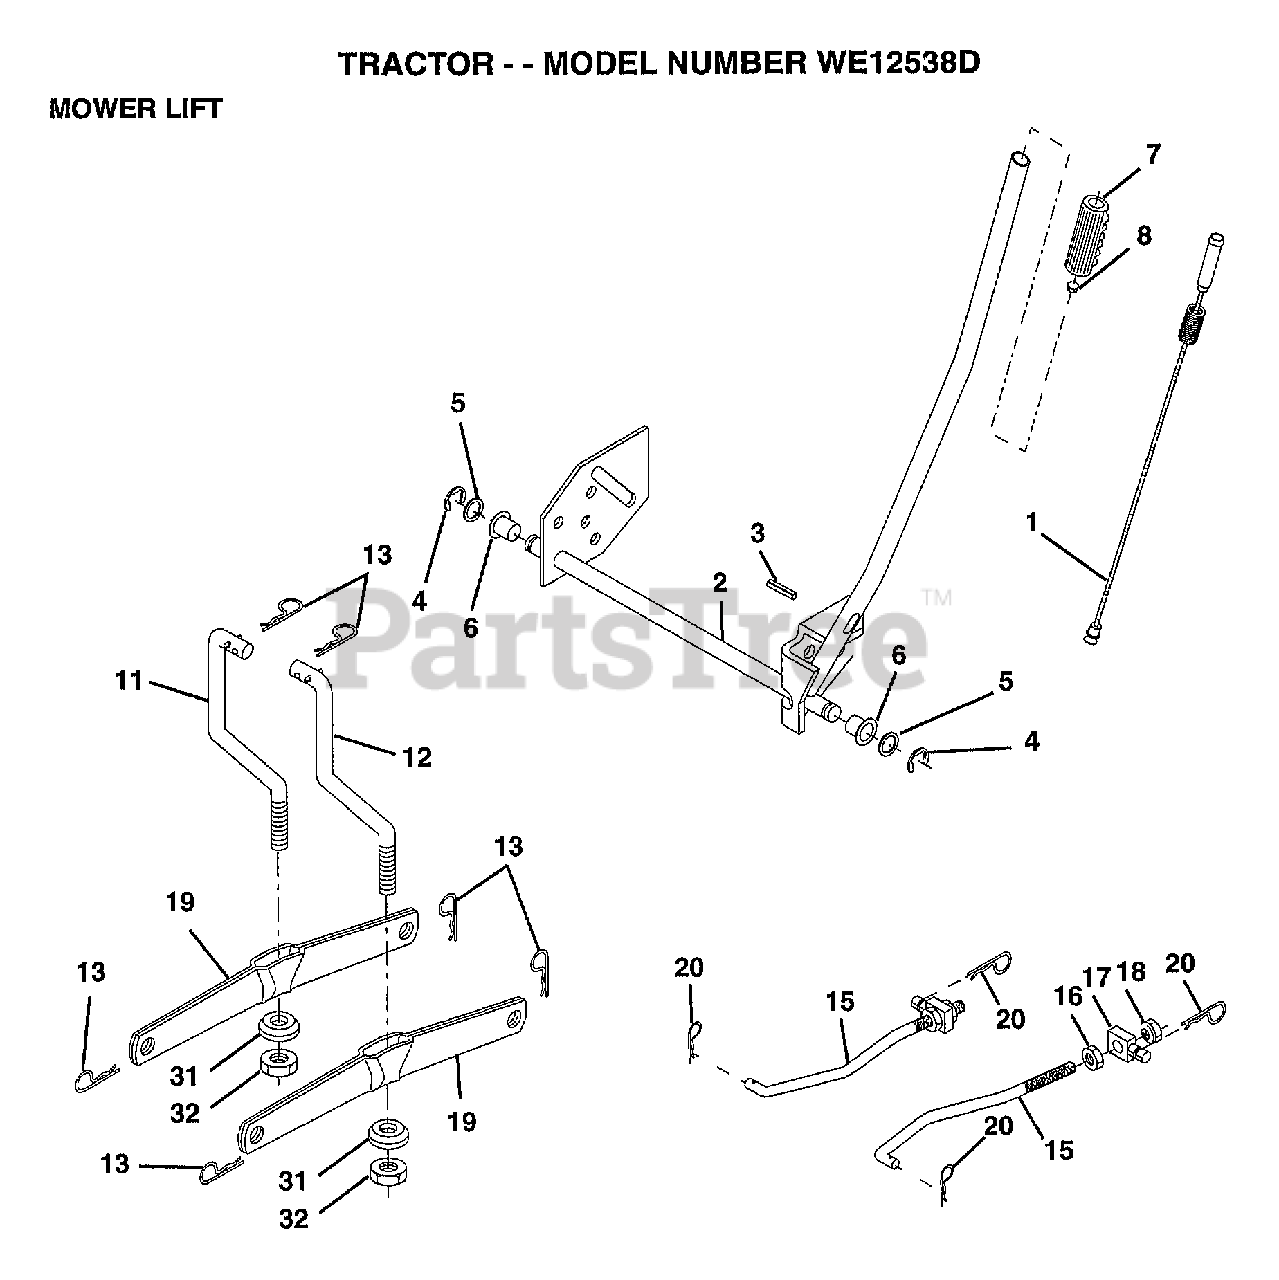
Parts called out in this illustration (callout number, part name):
1	WIRE ASM W.SPRING
2	SHAFT ASM LIFT RH
3	PIN-GROOVE LT
5	WASHER
6	NYLON BEARING
7	GRIP
15	LINK.FRONT
16	NUT
17	TRUNION
18	NUT.LK.W/WSH.1/2.
19	ARM SUSP REAR
20	RETAINER.SPRING
31	BEARING PVT LH
32	NUT.CROWNLOCK.3/8
